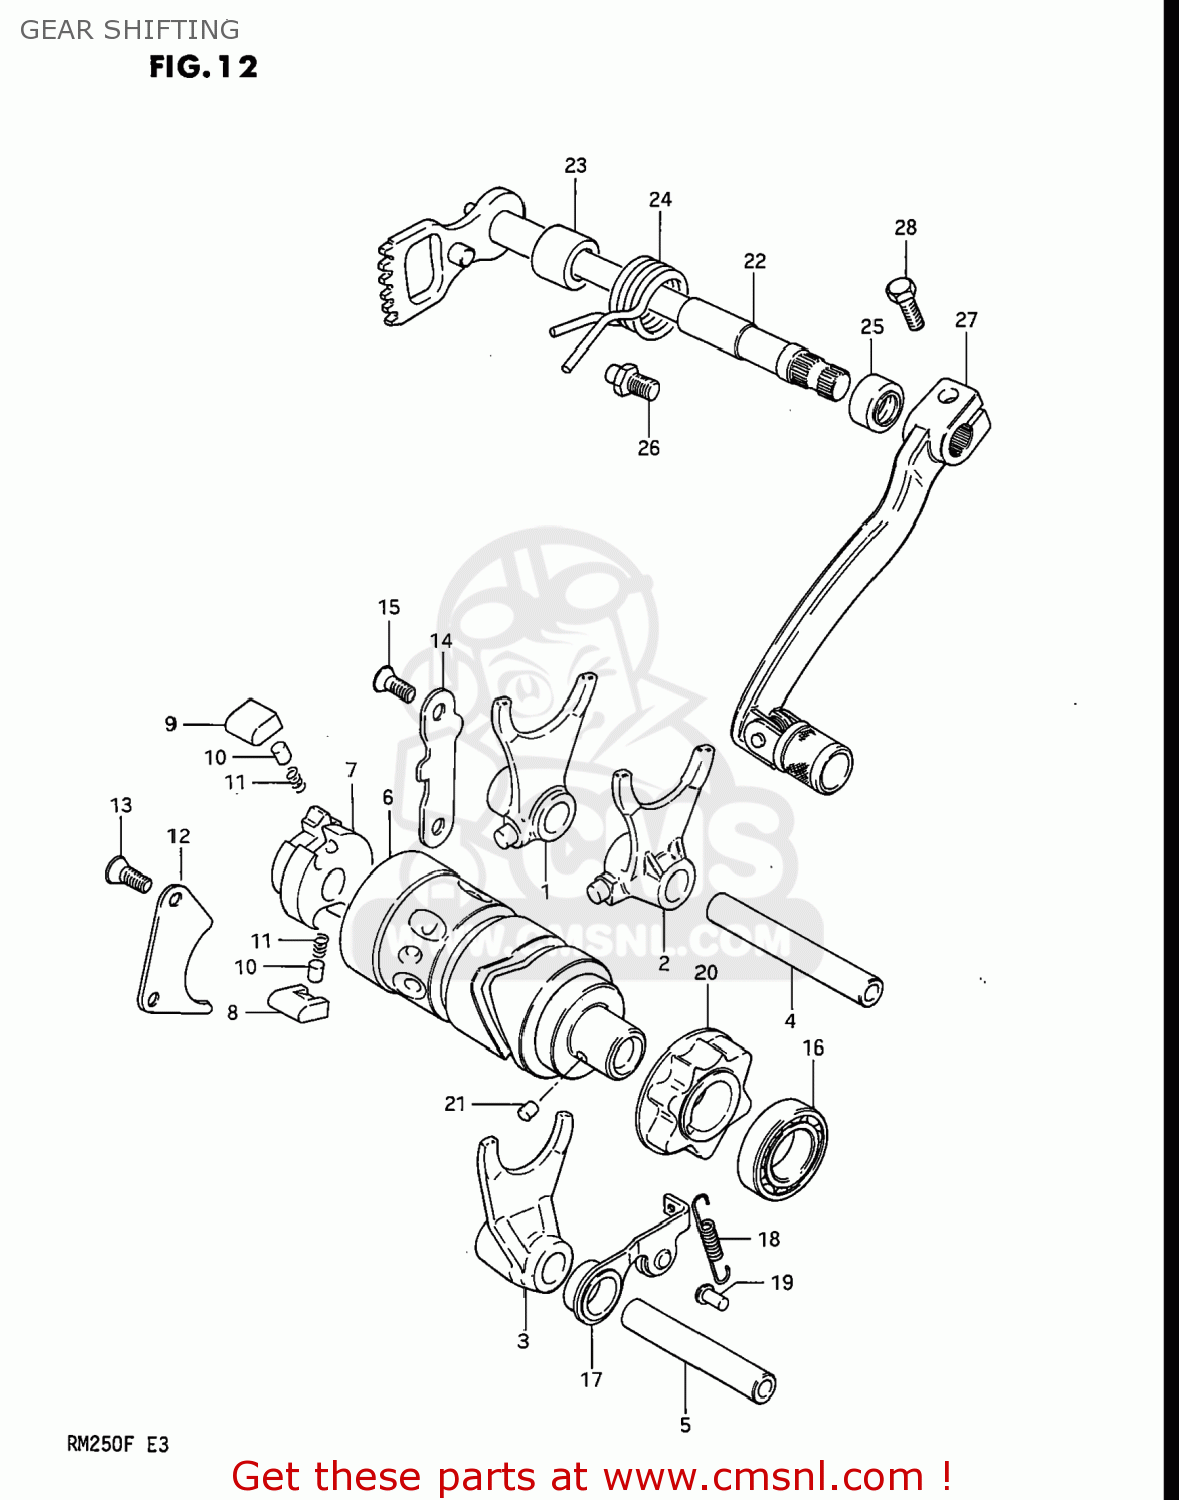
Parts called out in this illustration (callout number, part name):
1	FORK,GEAR SHIFT NO.1
2	FORK,GEAR SHIFT NO.2
3	FORK,GEAR SHIFT NO.3
4	SHAFT,GEAR SHIFT FORK
5	SHAFT,GEAR SHIFT FORK NO.2
6	CAM,GEAR SHIFT
7	GEAR,GEARSHIFT CAM DRIVE
8	PAWL,GEAR SHIFT NO.1
9	PAWL,GEAR SHIFT NO.2
10	PIN(5X8)
11	SPRING
12	LIFTER,GEAR SHIFT PAWL
13	SCREW
14	GUIDE,GEAR SHIFTING CABLE
15	SCREW
16	BEARING
17	STOPPER,GEAR SHIFTING CAM
18	SPRING
19	RIVET
20	PLATE,GEAR SHIFT CAM STOPPER
21	PIN
22	SHAFT,GEAR SHIFT
23	SPACER(12X20X15.3)
24	SPRING
25	OIL SEAL
26	STOPPER,GEAR SHIFT CAM
27	LEVER ASSEMBLY,GEAR SHIFTING
28	BOLT
